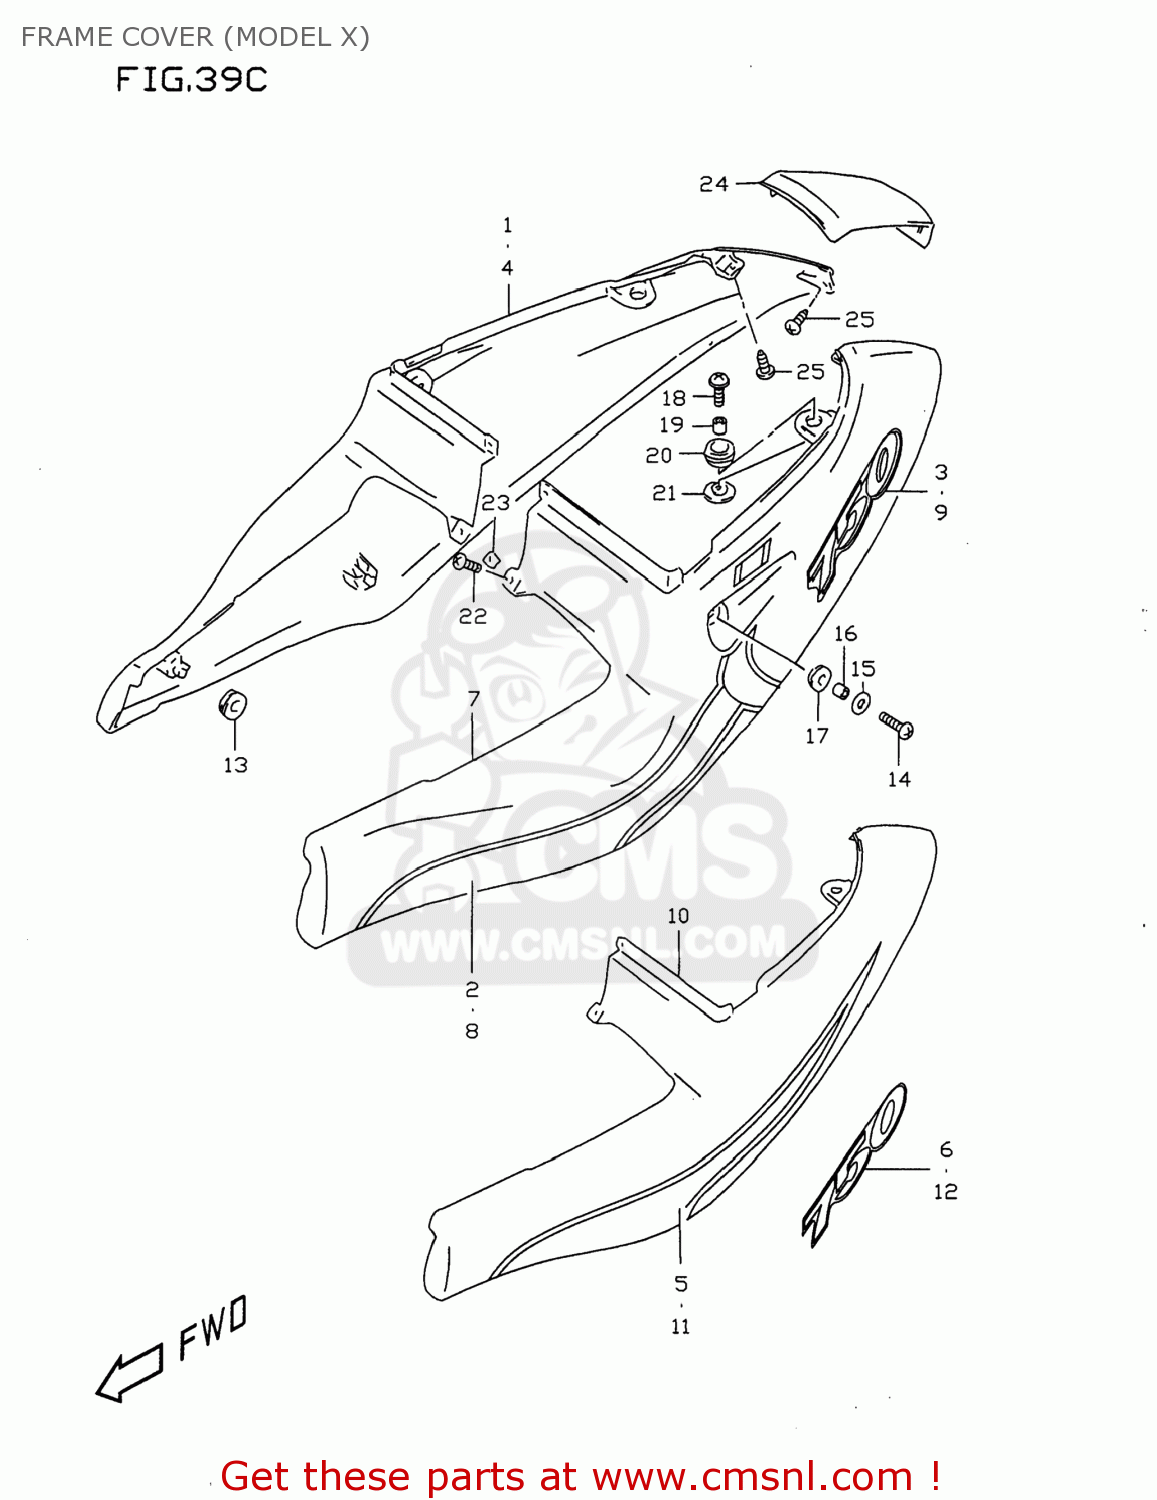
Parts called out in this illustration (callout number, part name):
1	COVER,FRAME,R(WHITE)
2	TAPE,FRAME COVER,R
3	EMBLEM,750
4	COVER,FRAME,R(BLACK)
5	TAPE,FRAME COVER,R
6	EMBLEM,750
7	COVER,FRAME,L(WHITE)
8	TAPE,FRAME COVER,L
9	EMBLEM,750
10	COVER,FRAME,L
11	TAPE,FRAME COVER,L
12	EMBLEM,750
13	CUSHION
14	SCREW(6X20)
15	WASHER(6.5X22X1.6)
16	SPACER(6.5X9X6.7)
17	CUSHION
18	SCREW(6X25)
19	SPACER(6.5X10X9.4)
20	CUSHION,TAIL COVER UPR
21	CUSHION,FRAME COVER LWR
22	SCREW
23	NUT
24	COVER,FRAME CTR
25	SCREW
